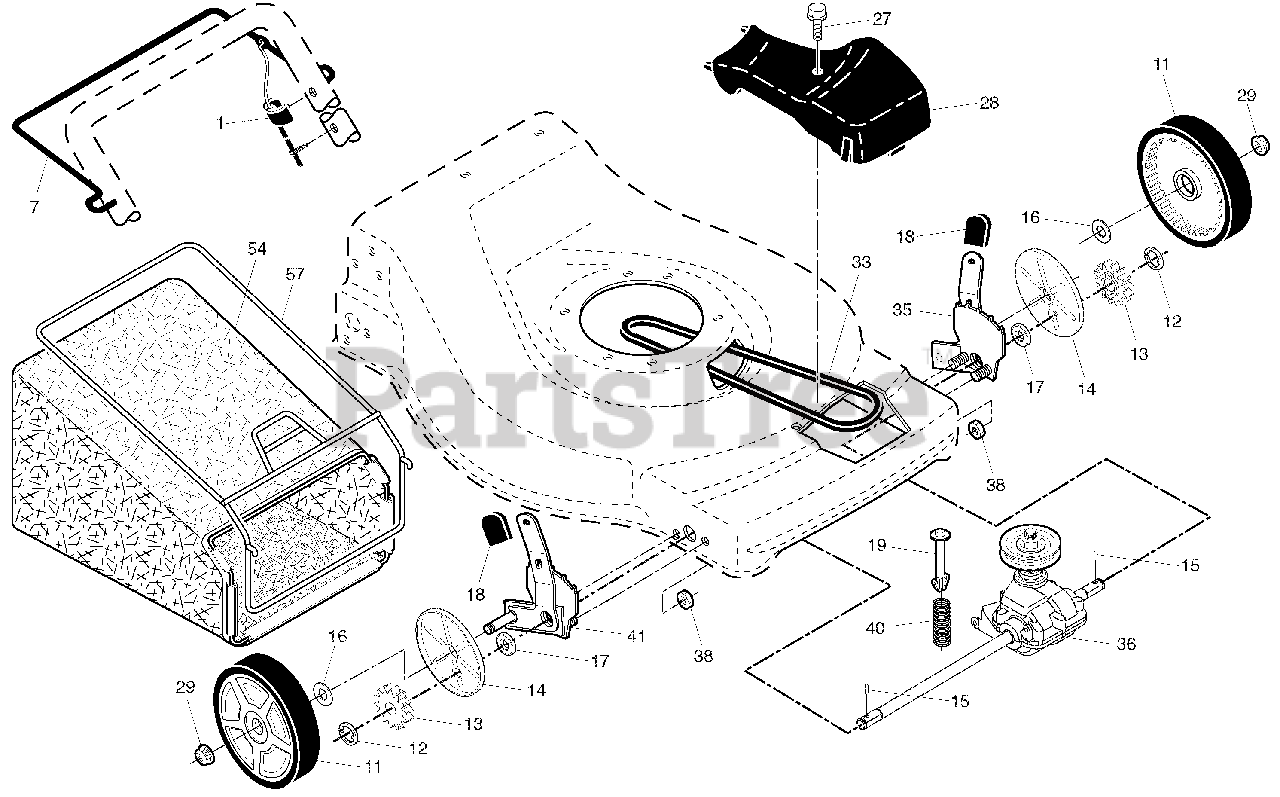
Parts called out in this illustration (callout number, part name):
1	CABLE, DRIVE CONTROL
7	Control Bar, Drive
11	WHEEL AND TIRE ASSEMBLY-FRONT
14	Dust Cover
15	Pawl, Drive
16	Washer, Flat 3/8
17	BEARING
18	Selector Knob
19	Retainer, Spring
27	Pan Head Tapping Screw #10-24
28	DRIVE COVER
29	Nut, Hex
33	DRIVE BELT
35	KIT,WHEEL ADJUSTER, RH (INCLUD
36	Gear Case Assembly, Complete
38	Lock Nut 1/4-20
41	KIT,WHEEL ADJUSTER, RH (INCLUD
57	BAG FRAME
